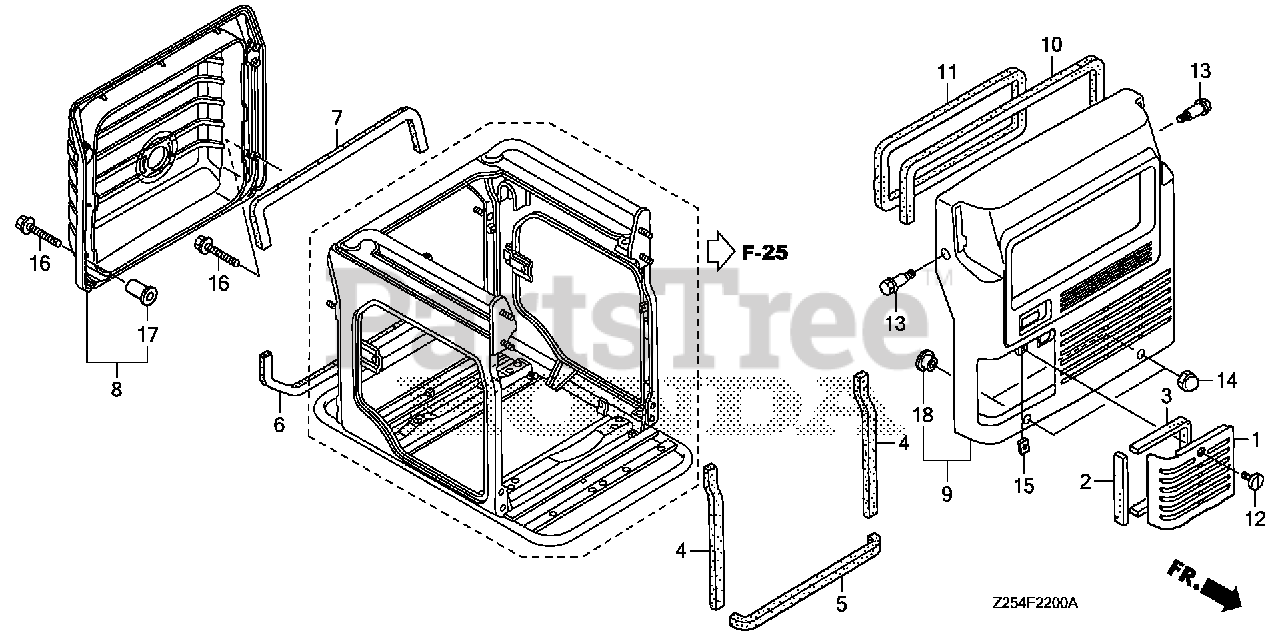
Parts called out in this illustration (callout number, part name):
1	COVER, MAINTENANCE *NH314* (CONDUCT GRAY)
2	SEAL A, MAINTENANCE COVER
3	SEAL B, MAINTENANCE COVER
4	SEAL (10X6X320)
5	SEAL (10X10X500)
6	SEAL (10X6X605)
7	SEAL (10X5X640)
8	COVER, RR. *NH314* (CONDUCT GRAY)
9	COVER, FR. *NH314* (CONDUCT GRAY)
10	SEAL A, FR. COVER
11	SEAL C, FR. COVER
12	BOLT, AIR CLEANER COVER (- SCREW)
12	SCREW, SPECIAL (6X16)
13	BOLT, SPECIAL (6X26)
14	NUT, OPEN STAY (6MM)
15	NUT, SPRING (6MM)
16	BOLT, FLANGE (6X30)
17	COLLAR, AIR CLEANER SETTING
18	COLLAR, FR. COVER
